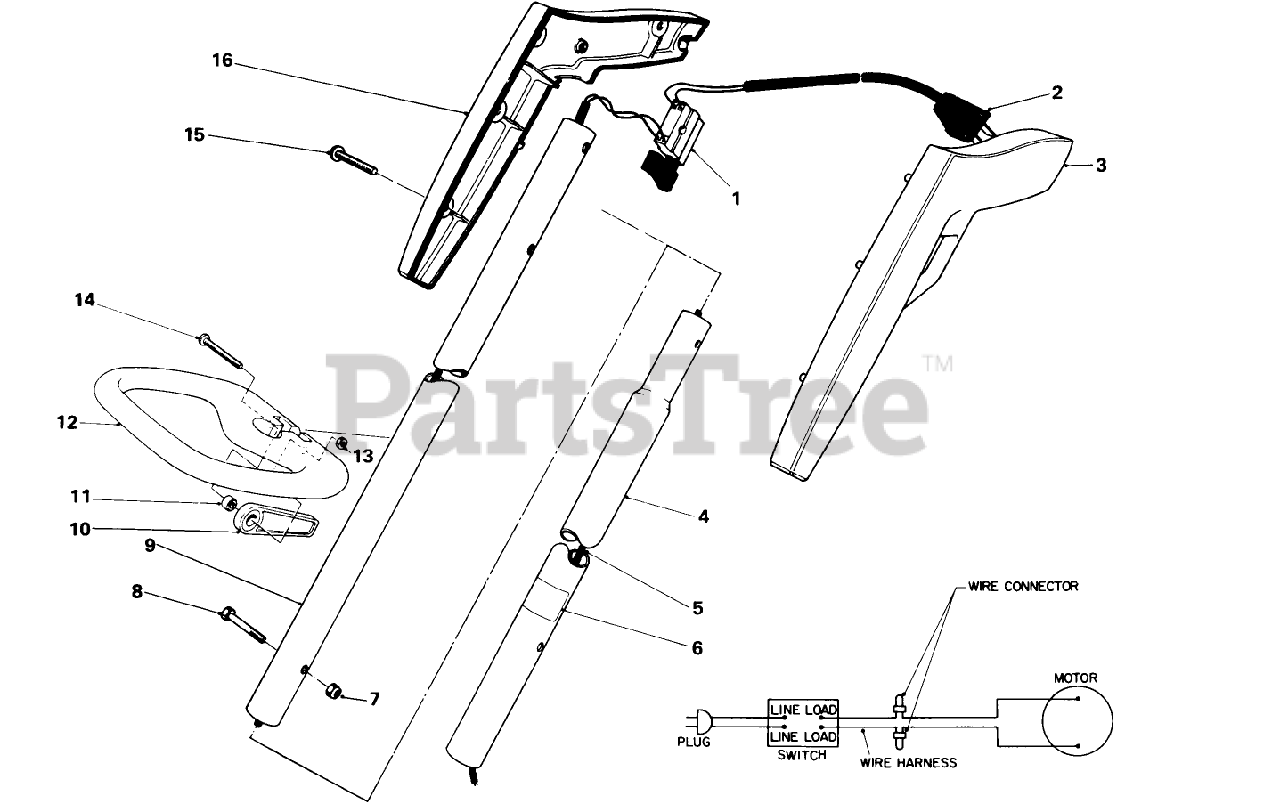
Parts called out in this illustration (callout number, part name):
1	SWITCH SINGLE SPEED
2	Power Cord
3	Grip L.H.
4	Tubing-Lower Extension
5	Wire Harness
6	Decal-Serial
7	NUT-LOCK, NI
8	HEX HD MACHINE SCREW
9	Oil Button
10	Cam Lock
11	Spacer
12	Support Handle
13	NUT-HEX
14	Screw
15	Screw
16	R.H. GRIP
